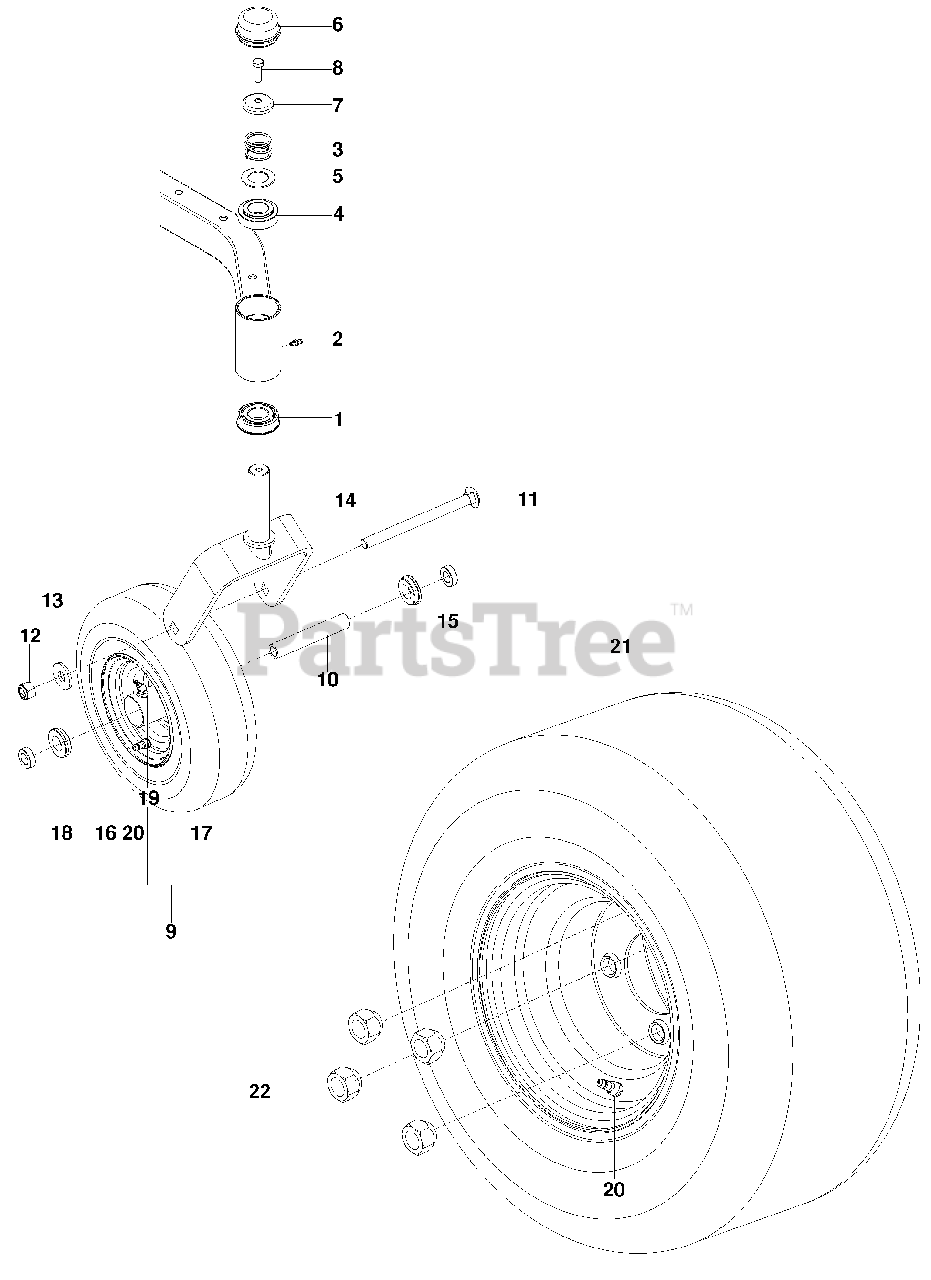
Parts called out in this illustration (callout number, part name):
1	BEARING, FLANGED
2	ZERK 3/16 DRIVE
3	SPRING, CASTER
4	BUSHING, CASTER
6	GREASE CAP
7	PLUG, CASTER
8	BOLT, HEX 5/16-18 x 1 NYLOC
9	CASTER TIRE ASSY
11	RHSNB 1/2-13 x 6 1/2
12	NUT 1/2-13 HEX NYLOC
13	WASHER 1/2 FLT
14	YOKE ORG
15	SPACER 5/16
17	CASTER TIRE, 410-5 4 PLY
18	BEARING, FLANGED
19	ZERK
20	VALVE STEM
21	WHEEL ASSY, REAR
22	NUT, LUG 1/2
